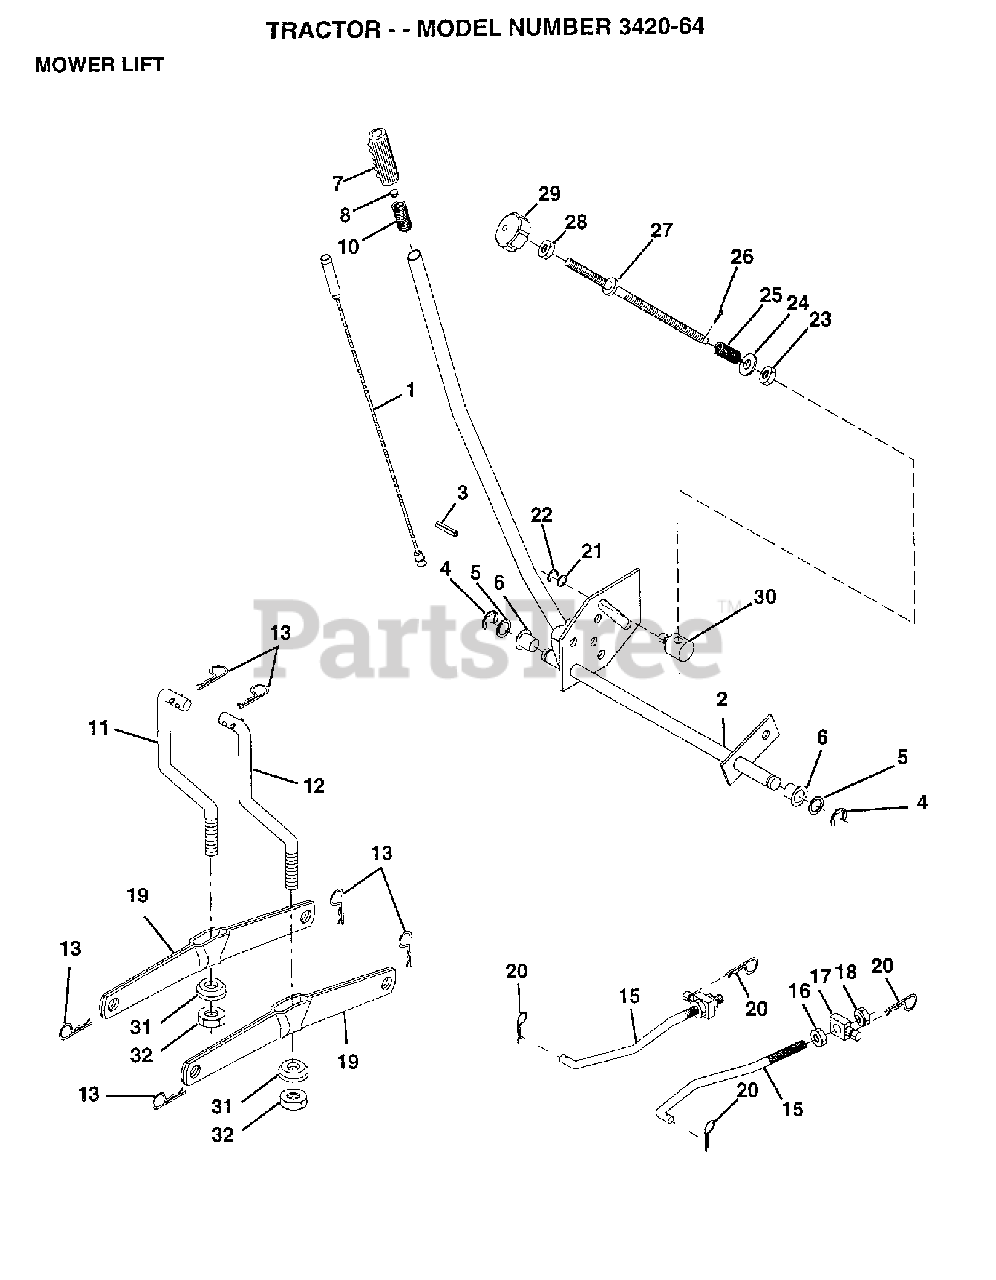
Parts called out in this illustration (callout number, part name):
1	WIRE.INNER.HANDLE.LIFT.LEVER
2	LIFT ARM ASSY
3	PIN GROOVE
4	RETAINING RING LT
6	BEARING.NYLON
7	GRIP
8	PLUNGER BUT KIT
10	SPRING, COMP T
11	LINK LIFT LH
12	Lift Link Assembly, RH
13	RETAINER SPRING
15	FRONT LINK
16	NUT.HEX.JAM.1/2-13
18	NUT.LK.W/WSH.1/2.
19	ARM.REAR.SUSPENSION
20	SPRING RETAINER
24	WASHER
25	SPRING.COMP.INF.H
27	ROD.LIFT.ADJUSTABLE
28	NUT
29	KNOB INF 3/8-16
30	TRUNNION
32	NUT CROWNLOCK 3/8-24
49	Flange Hex Lock Nut, 3/8-16
